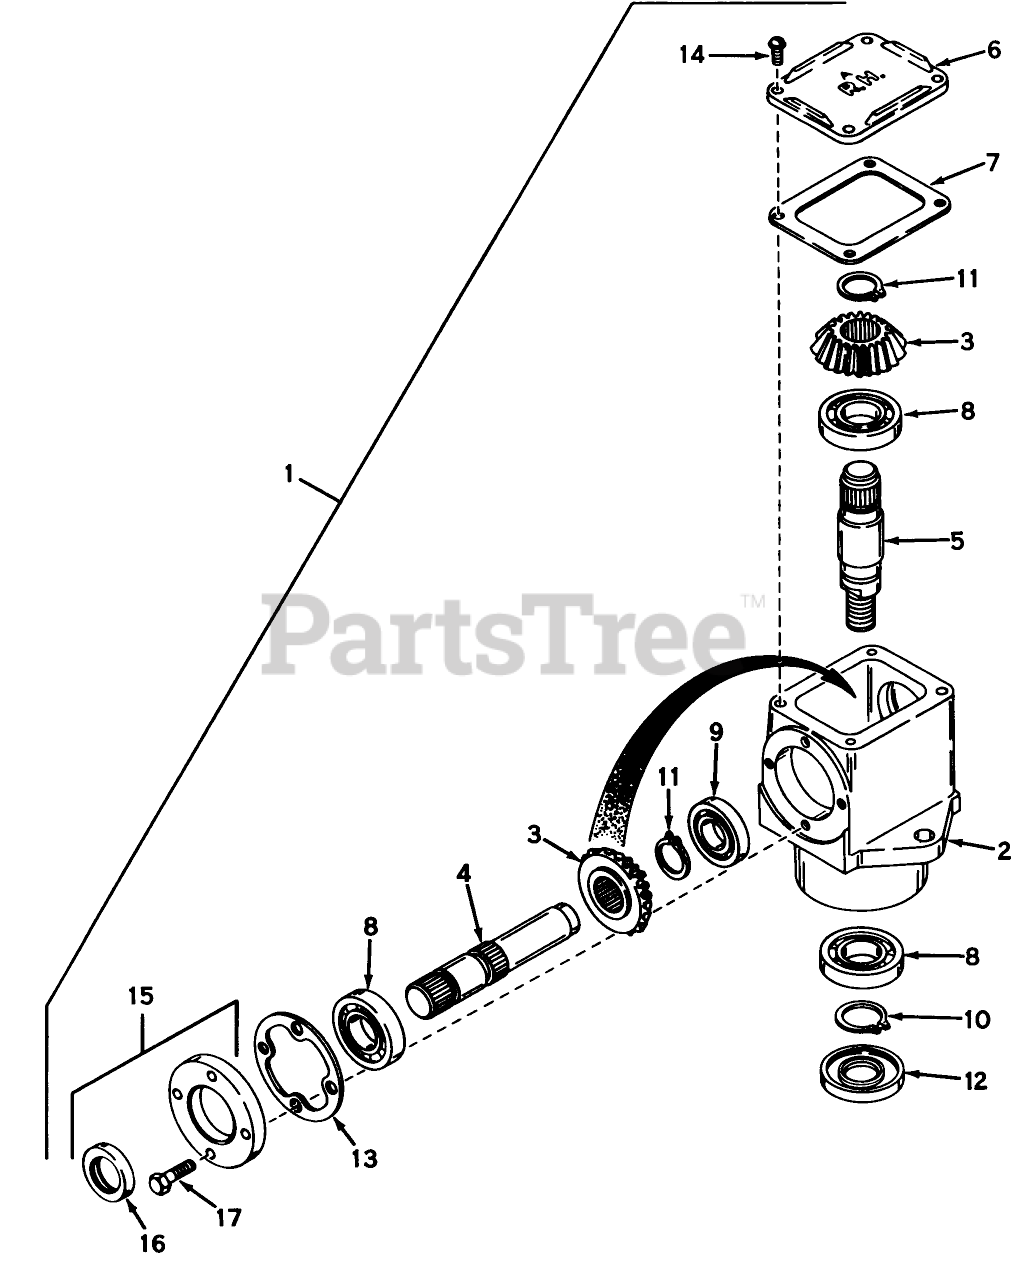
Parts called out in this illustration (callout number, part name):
1	Head Assy., Right Hand (Incl. Nos. 2 thru 15)
2	Housing, Right Angle Drive
3	Bevel Gear
4	Shaft, Input Pinion
5	Shaft, Output
6	Cover, Right Hand
7	Gasket
8	Bearing
9	Bearing
10	Ring-Snap
11	Ring-Snap
13	Gasket
14	Screw, Rd. Hd. Self Tap
15	Cap & Seal Assy., Retainer (Incl. Nos. 16 & 17)
16	Oil Seal
17	SCREW-HH
